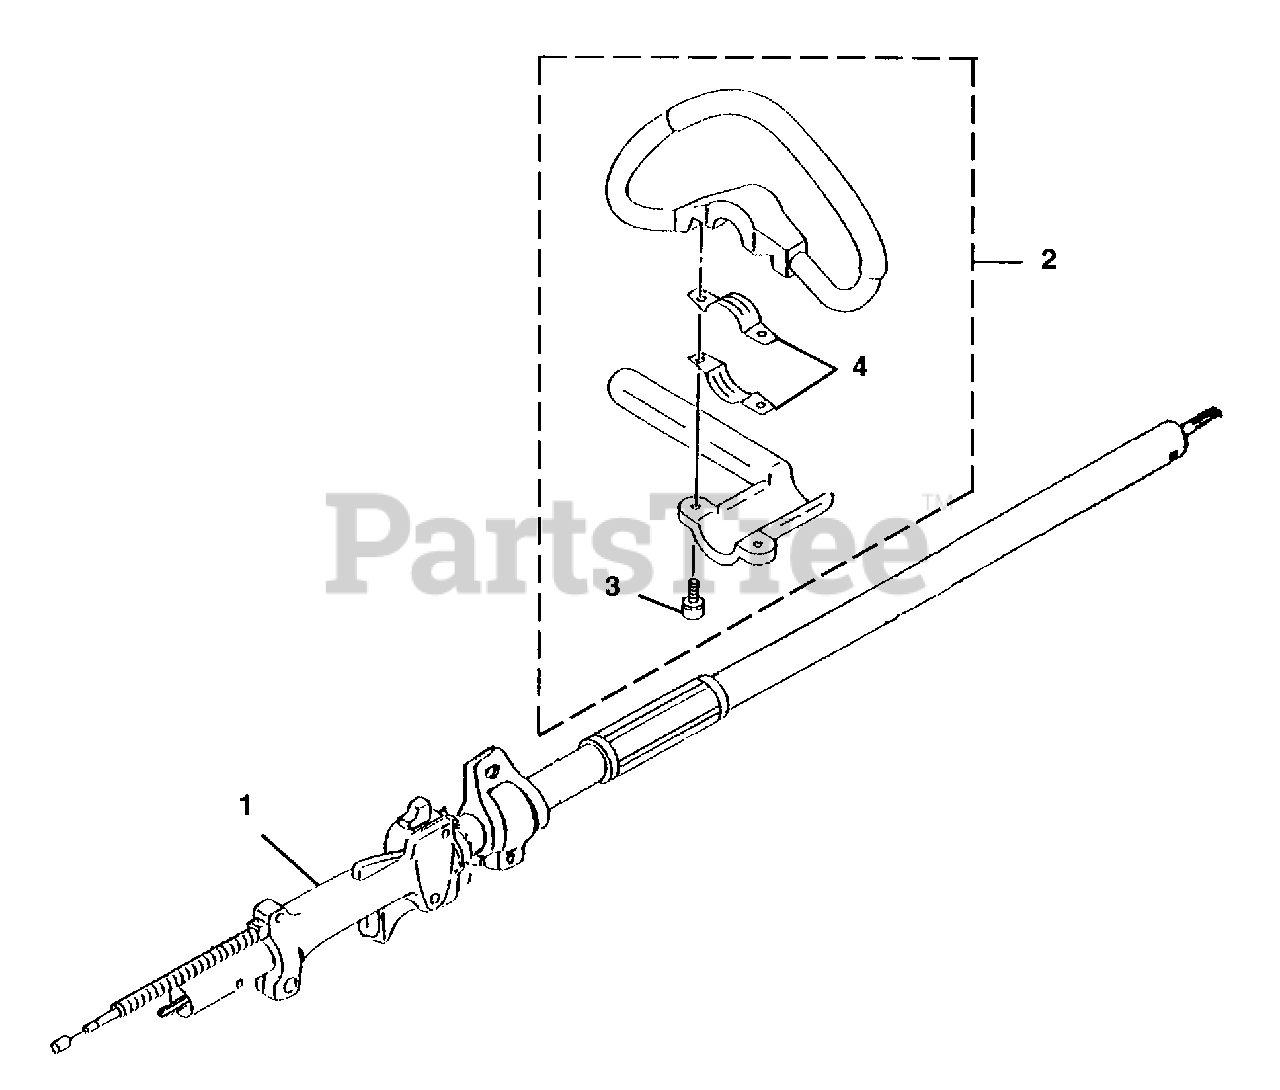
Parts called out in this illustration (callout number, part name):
1	CONTROL LEVER ASSEMBLY
2	HANDLE ASSEMBLY
3	BOLT-Socket Head
4	CLAMP - Handle Bar
